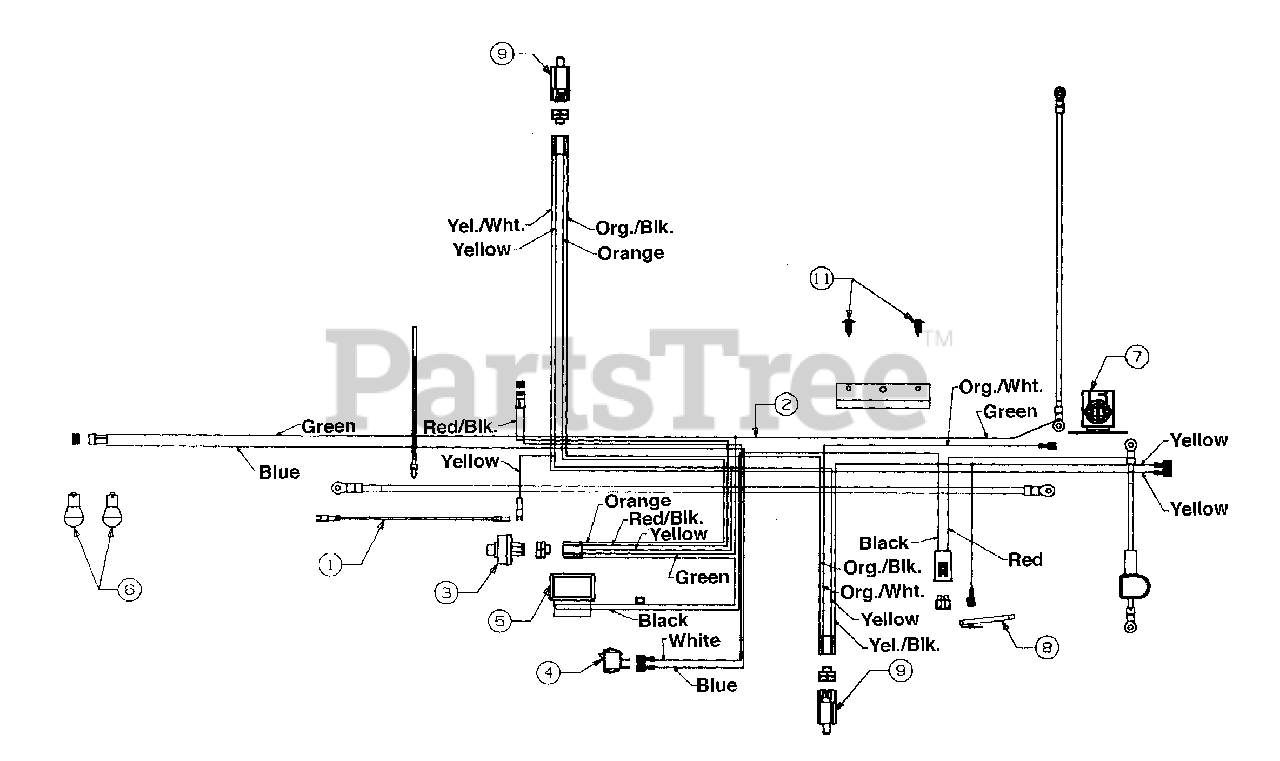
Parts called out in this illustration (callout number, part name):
1	Harness Adapter (Mag.)
2	Wire Harness w/Light Switch and Amp
3	Ignition Switch
4	Light Switch
5	Ammeter
6	Bulb (Headlight)
7	Solenoid
8	Safety Switch (Reverse)
9	Safety Switch
11	Ratchet
